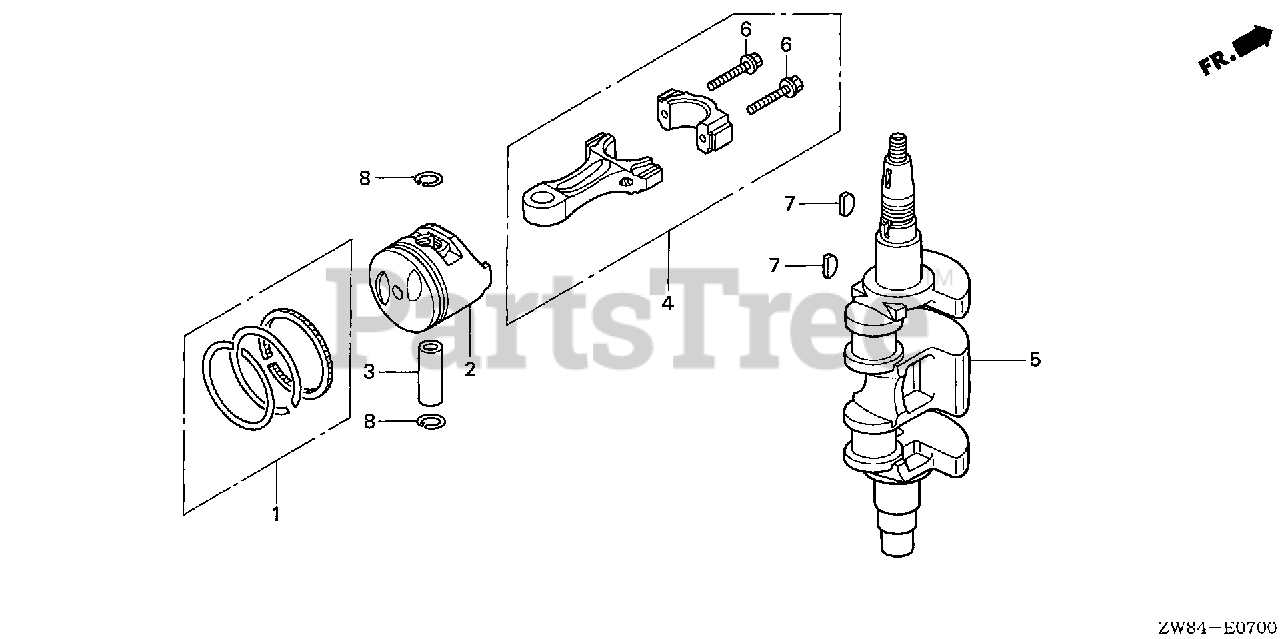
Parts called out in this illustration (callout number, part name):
1	RING SET, PISTON (STD)
3	PIN, PISTON
4	ROD, CONNECTING
5	CRANKSHAFT
6	BOLT, CONNECTING ROD (6X34)
7	KEY, SPECIAL (16X13)
8	CLIP, PISTON PIN (16MM)
